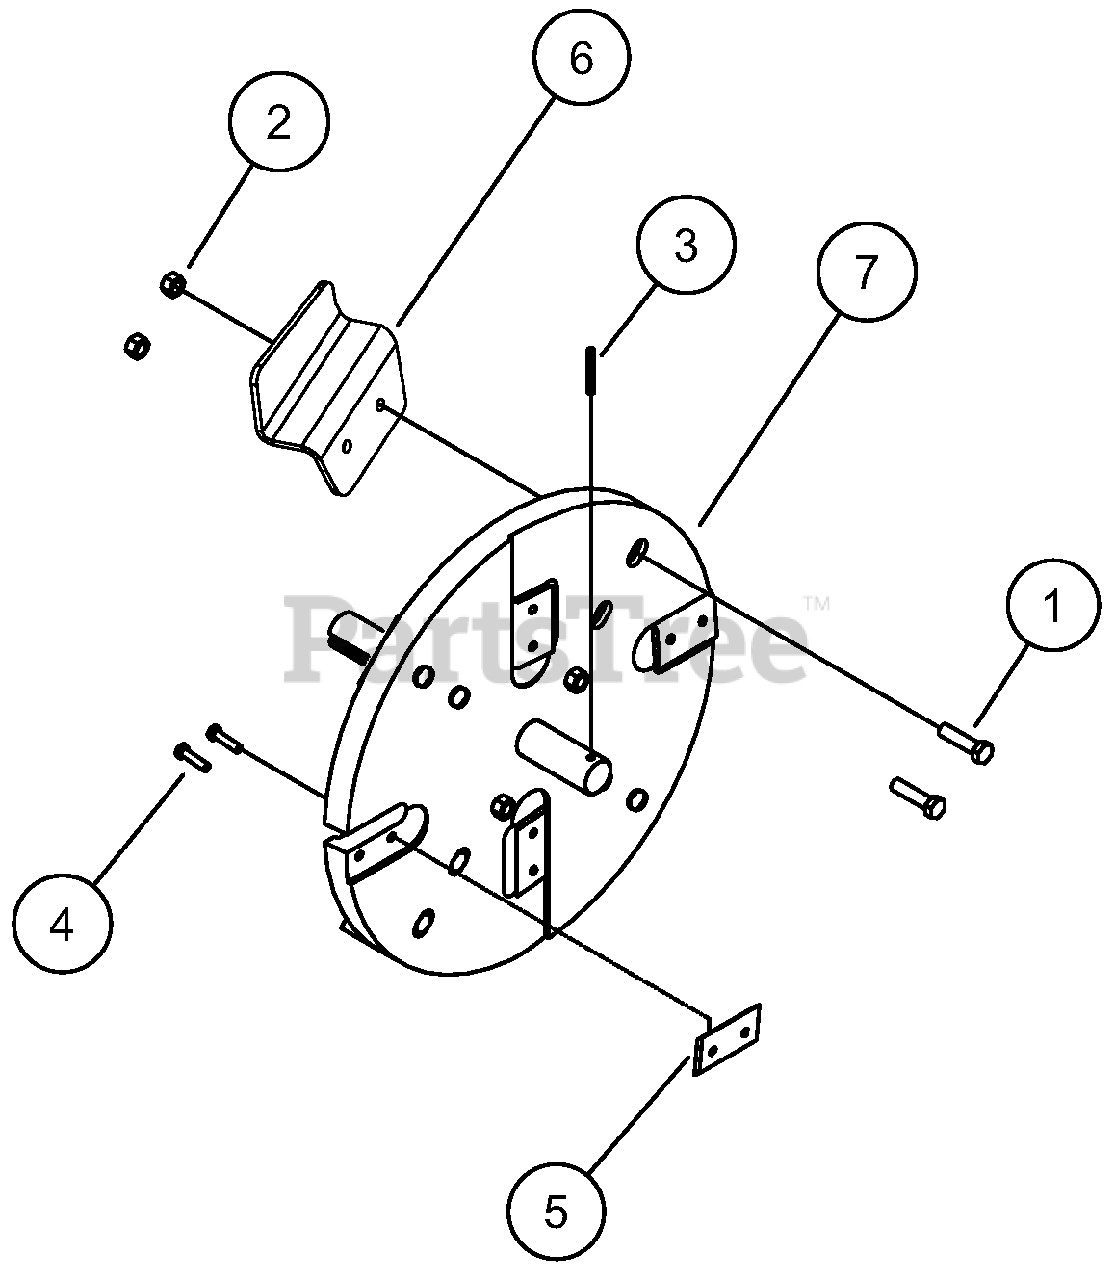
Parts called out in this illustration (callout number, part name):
1	BOLT, 1/2 X 2 HEX HD GR5 ZP
2	NUT, 1/2 CENTERLOCK GRB ZP
3	SPRING PIN, 1/4 X 2 LONG
4	BOLT, 5/16 X 1-1/4 HHD GR8 PATCH
5	KIT, CHIPPER BLADE
6	FORMED PADDLE, 5 INCH CHIPPER
7	WELDMENT, CHIPPER ROTOR
